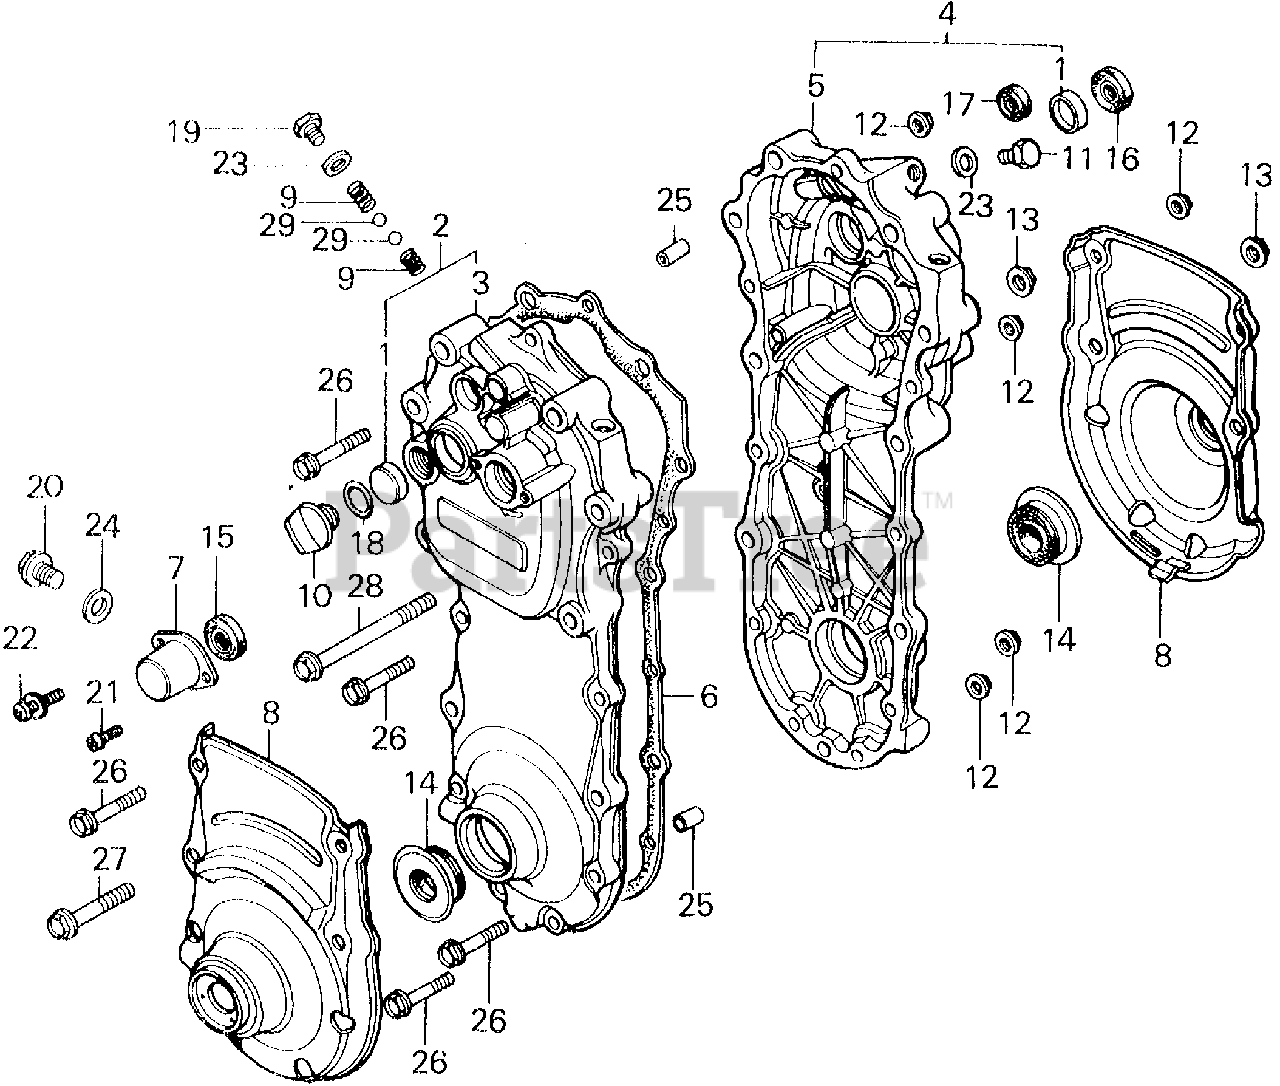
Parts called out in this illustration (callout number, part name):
1	PLUG, SEALING (30MM)
2	CASE ASSY., R. TRANSMISSION
3	CASE, R. TRANSMISSION
4	CASE ASSY., L. TRANSMISSION (NOT AVAILABLE)
5	CASE, L. TRANSMISSION
6	GASKET, TRANSMISSION CASE
7	COVER, P.T.O.
8	PROTECTOR, CASE
8	PROTECTOR, CASE (NOT AVAILABLE)
9	SPRING, BALL SETTING
11	BOLT, HEX. (8X10)
12	NUT, FLANGE (6MM)
13	NUT, FLANGE (8MM)
14	SEAL, WATER (48X32X19)
14	SEAL, WATER
15	OIL SEAL (17X30X8)
16	OIL SEAL (15X30X7)
17	OIL SEAL (12X22X6)
18	O-RING (16MM)
19	BOLT, HEX. (8X10)
20	BOLT, DRAIN PLUG (12MM)
22	SCREW-WASHER (6X12)
23	WASHER, PLAIN (8MM)
24	WASHER, DRAIN PLUG (12MM)
25	PIN A, DOWEL (8X14)
26	BOLT, FLANGE (6X35)
27	BOLT, FLANGE (8X40)
28	BOLT, FLANGE (8X80)
29	BALL, STEEL (#8) (1/4)
